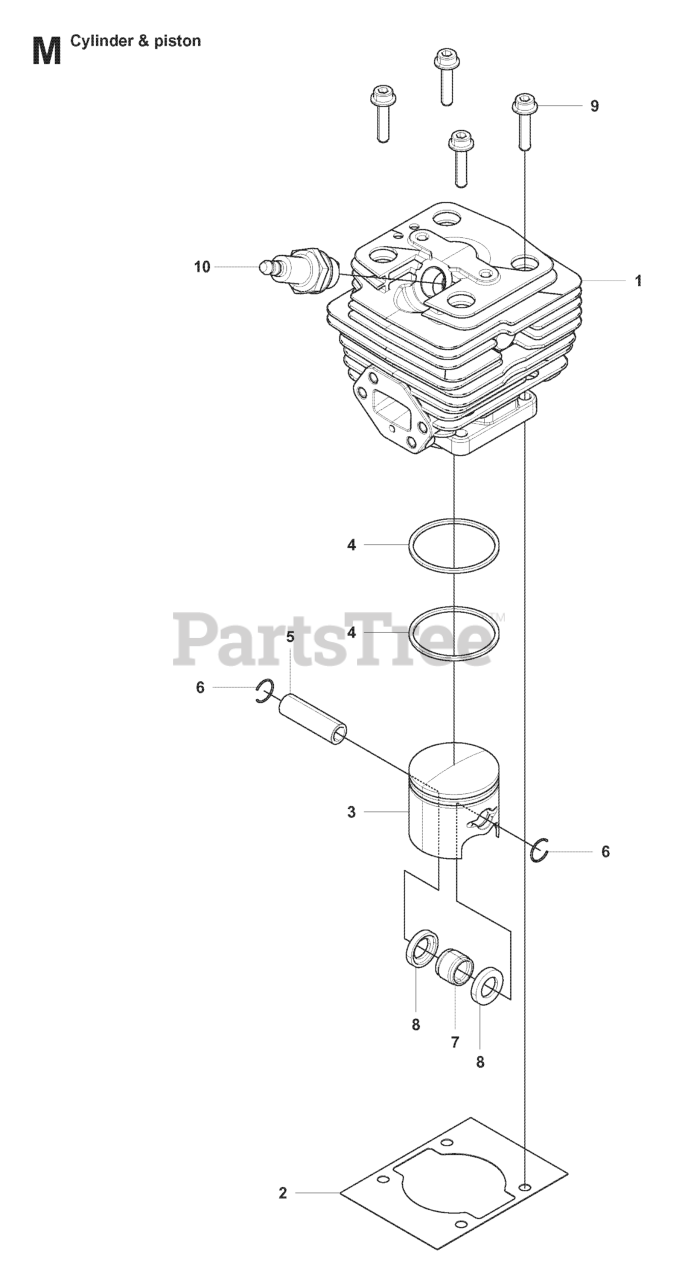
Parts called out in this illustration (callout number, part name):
4	RING
5	PISTON PIN
7	ROLLER BEARING
10	SPARK PLUG M14X1.25 NGK BPMR7A
